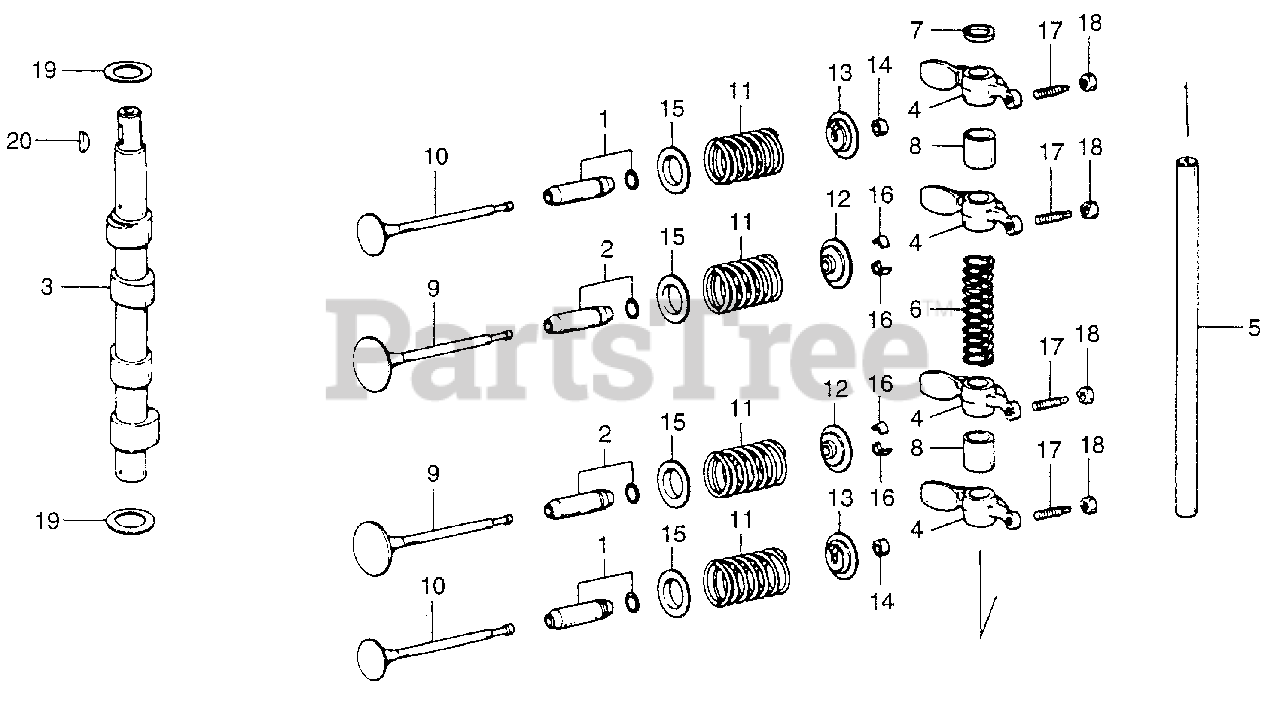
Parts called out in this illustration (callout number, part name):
1	GUIDE, VALVE
2	GUIDE, VALVE (NOT AVAILABLE)
3	CAMSHAFT (NOT AVAILABLE)
4	ARM, VALVE ROCKER
5	SHAFT, VALVE ROCKER ARM
6	SPRING, VALVE ROCKER ARM
7	COLLAR A, VALVE ROCKER ARM
8	COLLAR B, VALVE ROCKER ARM
9	VALVE, IN.
10	VALVE, EX.
11	SPRING, VALVE
12	RETAINER, VALVE SPRING (NOT AVAILABLE)
13	RETAINER, VALVE SPRING
14	ROTATOR, VALVE
15	SEAT, VALVE SPRING
16	COTTER, VALVE
17	SCREW, TAPPET ADJ.
18	NUT, TAPPET ADJ.
19	WASHER, THRUST (16MM)
20	KEY, WOODRUFF (16X12)
